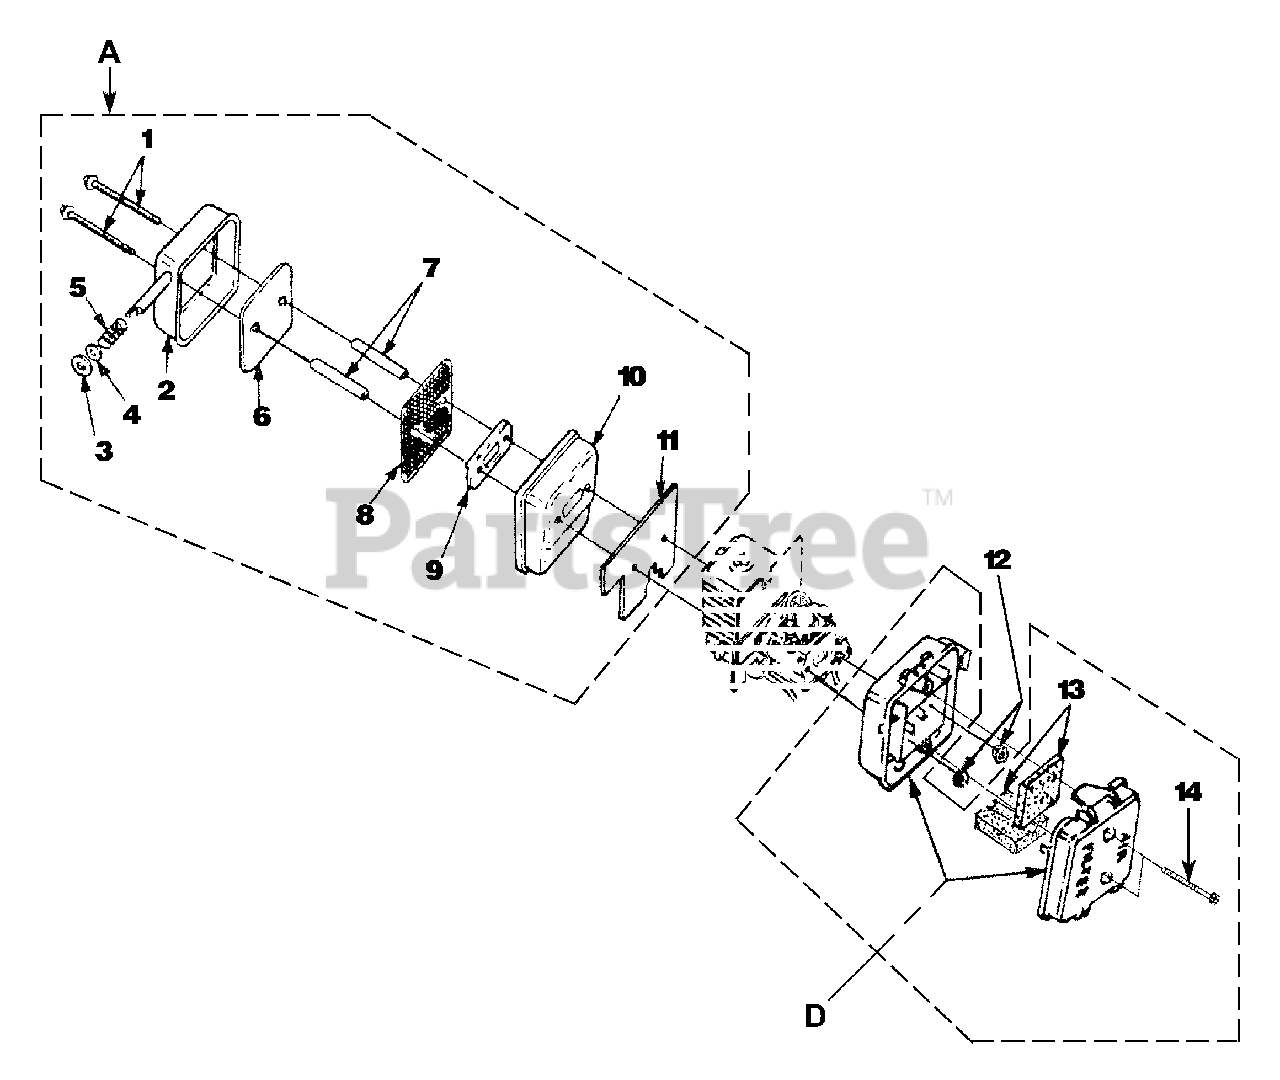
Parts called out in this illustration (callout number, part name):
1	SCREW-Sems Hex Hd. (10-24 x 2 1/2")
2	MUFFLER COVER
3	WASHER-Insulating
4	WASHER-Flat
5	SPRING-Compression
6	DEFLECTOR-Muffler
7	SPACER-Muffler
8	SCREEN-Spark Arrestor
9	PLATE-Reinforcing
10	BODY-Muffler
11	GASKET-Muffler
12	NUT-Hex (10-24)
13	AIR FILTER
14	SCREW-Thd. Form. (#8-16 x 3/4")
A	MUFFLER-Complete
D	AIR FILTER KIT
